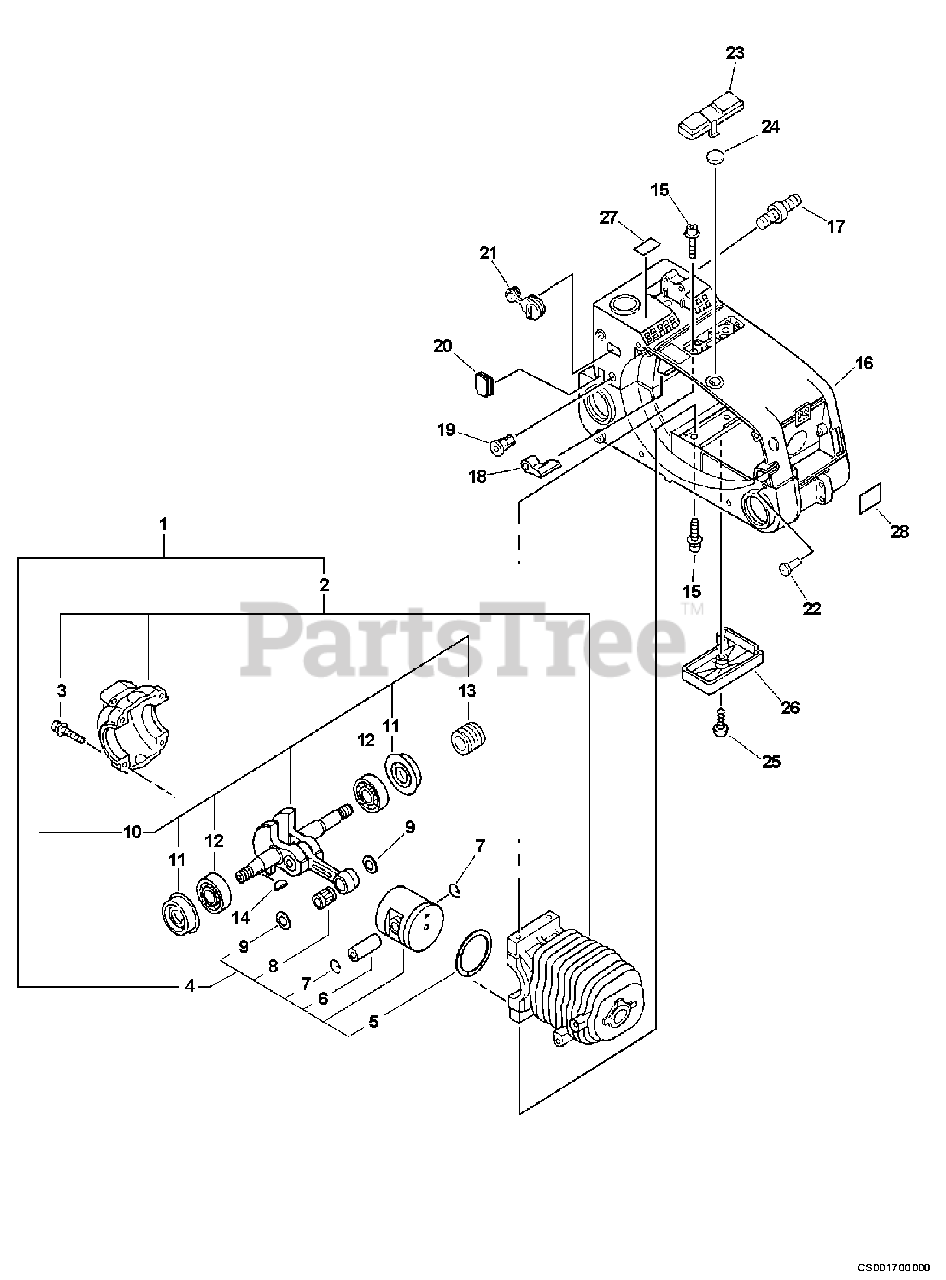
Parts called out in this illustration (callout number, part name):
1	SHORT BLOCK
2	CRANKCASE KIT
3	SCREW 5×25
4	PISTON KIT
5	RING, PISTON
6	PIN, PISTON
7	RING, SNAP
8	BEARING, NEEDLE 8
9	WASHER, THRUST
10	CRANKSHAFT ASSY
11	SEAL, OIL 12
12	BEARING, BALL - 6201 C3
13	GEAR, WORM
14	KEY, WOODRUFF
15	BOLT 5×16
16	COVER, ENGINE - GRAY
17	BOLT, STUD 6
19	GROMMET, IDLE
21	GROMMET, CHOKE
22	VENT ASSY
25	SCREW 4×16
27	LABEL, PURGE PUMP
28	LABEL, CAUTION - HOT
